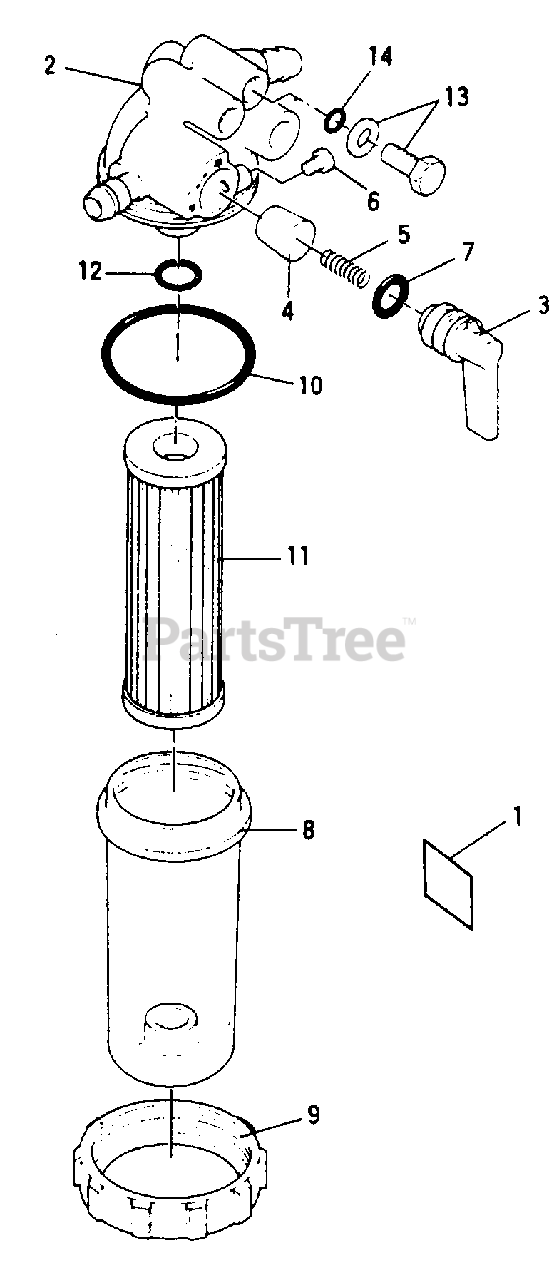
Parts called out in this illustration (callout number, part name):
1	Label, Fuel Filter
5	Spring, Valve
7	O-Ring, Lever
8	Cup, Filter
10	O-Ring, Filter Cup
11	Element
12	O-Ring, 10 X 13.6MM
13	Plug, Breather
